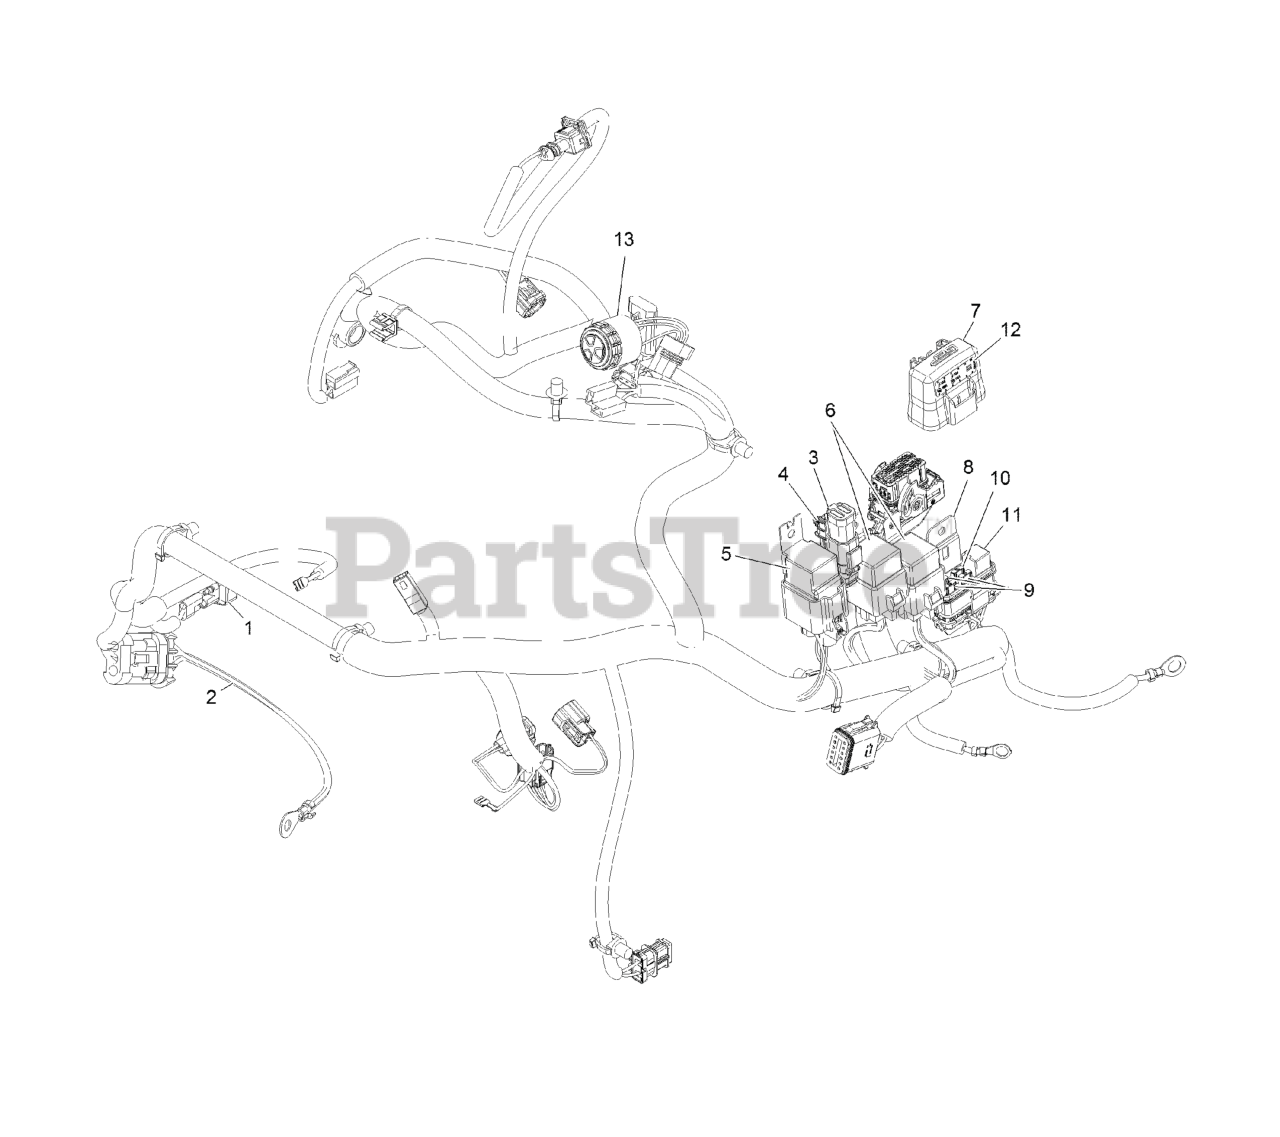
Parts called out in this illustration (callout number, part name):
2	HARNESS-WIRE, FUSIBLE LIN
3	Connector (6M)
4	CLIP-CONNECTOR
5	RELAY-70A
6	RELAY-MINI
7	COVER-BLOCK, FUSE
8	CLIP-MOUNTING
9	FUSE-MINI BLADE, 15 AMP
10	FUSE-MINI BLADE, 10 AMP
11	RELAY-MICRO
12	DECAL-FUSE
13	ALARM-DUAL TONE
